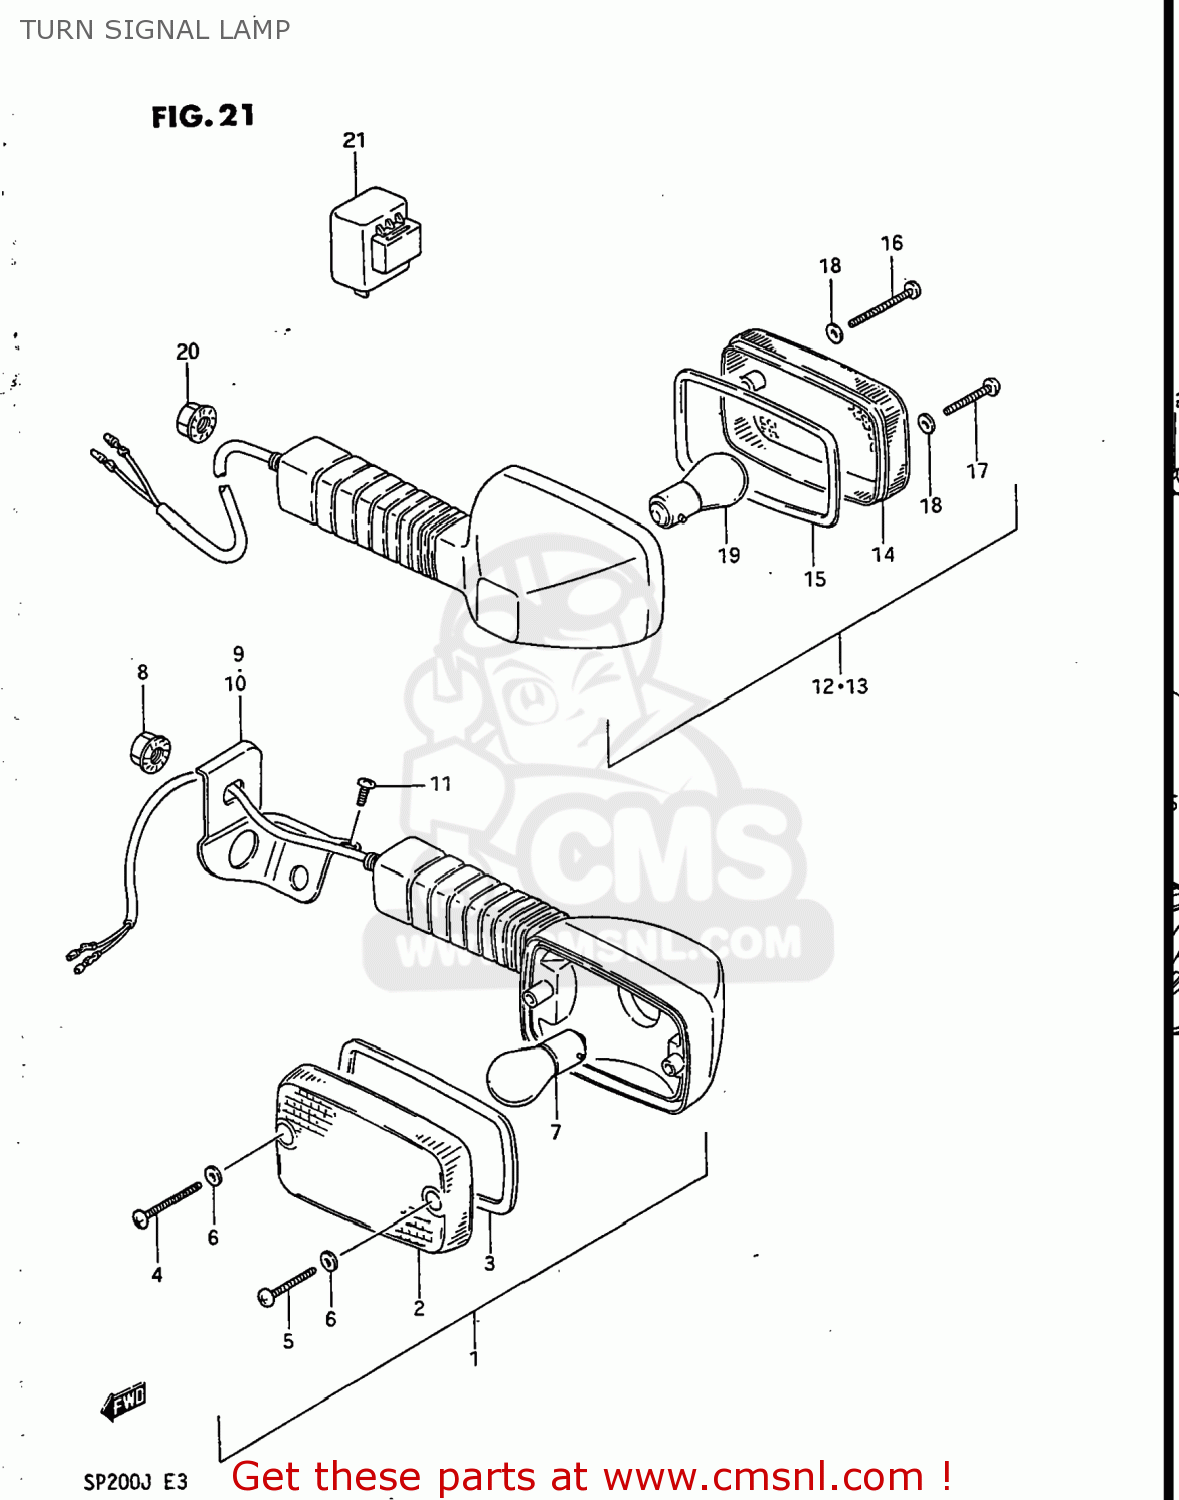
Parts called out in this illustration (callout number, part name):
1	LAMP ASSEMBLY,FRONT TURN SIGNAL
2	LENS,FR
3	GASKET (NAS)
4	SCREW,TURN SIG LENS FITTING
5	SCREW
6	GASKET (NAS)
7	BULB(12V23W,STANLEY,A4577A)
8	NUT
9	BRACKET,FRONT TURN SIGNAL,RIGHT
10	BRACKET,FRONT TURN SIGNAL
11	SCREW
12	LAMP ASSEMBLY,REAR TURN SIGNAL
13	LAMP ASSY,RR TURNSIGNAL
14	LENS,FR
15	GASKET (NAS)
16	SCREW,TURN SIG LENS FITTING
17	SCREW
18	GASKET (NAS)
19	BULB(12V23W,STANLEY,A4577A)
20	NUT
21	RELAY ASSEMBLY,TURN SIGNAL
